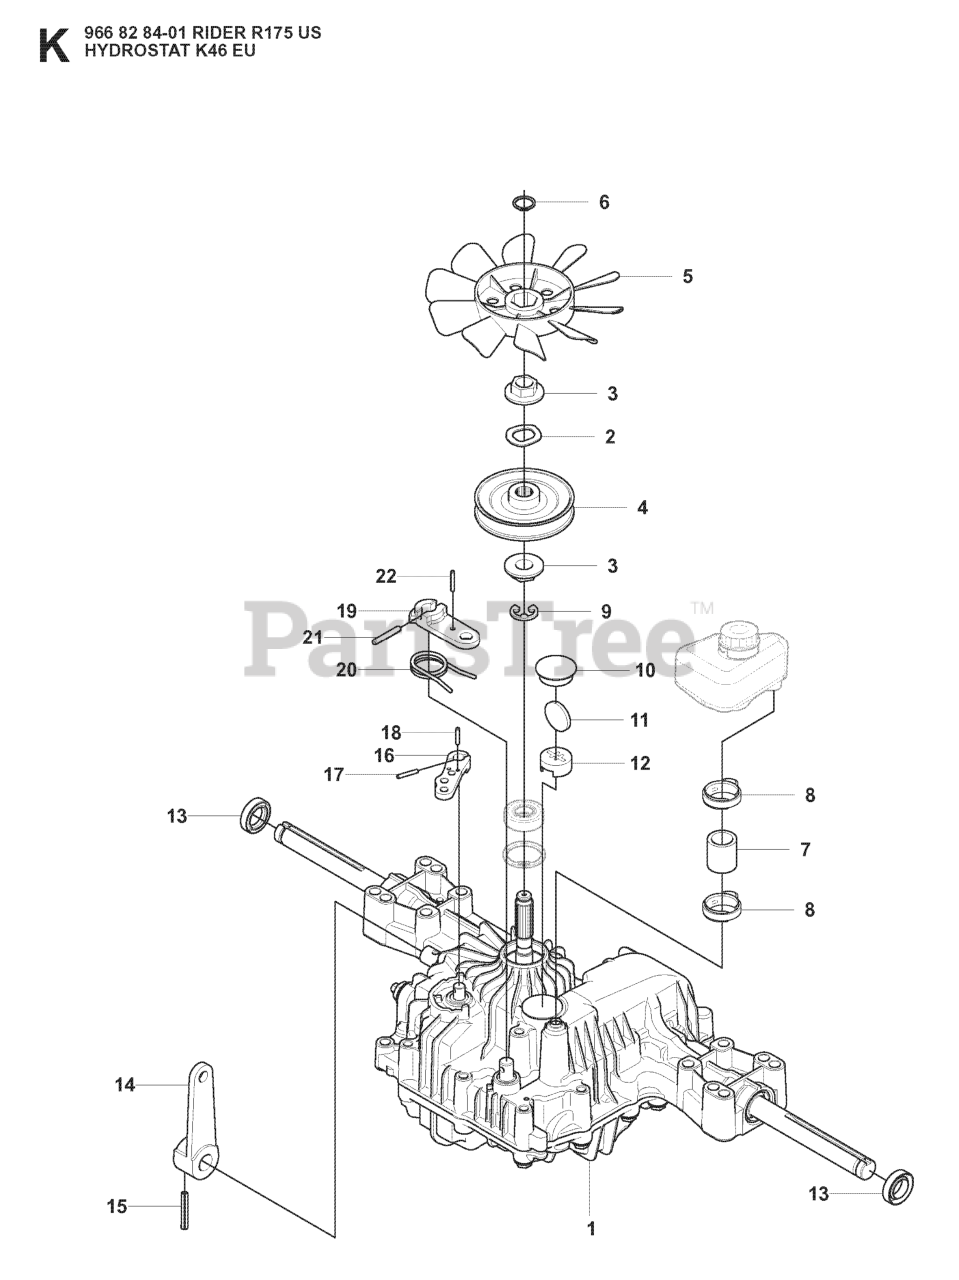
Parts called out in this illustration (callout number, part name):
1	HYDROSTAT 7A646024070
5	FAN.BLACK.1A646083070
6	RETAINING RING **
8	CLAMP
13	RP SEAL.19, 19216334280
14	CONTROL LEVER
20	RETURN SPRING
